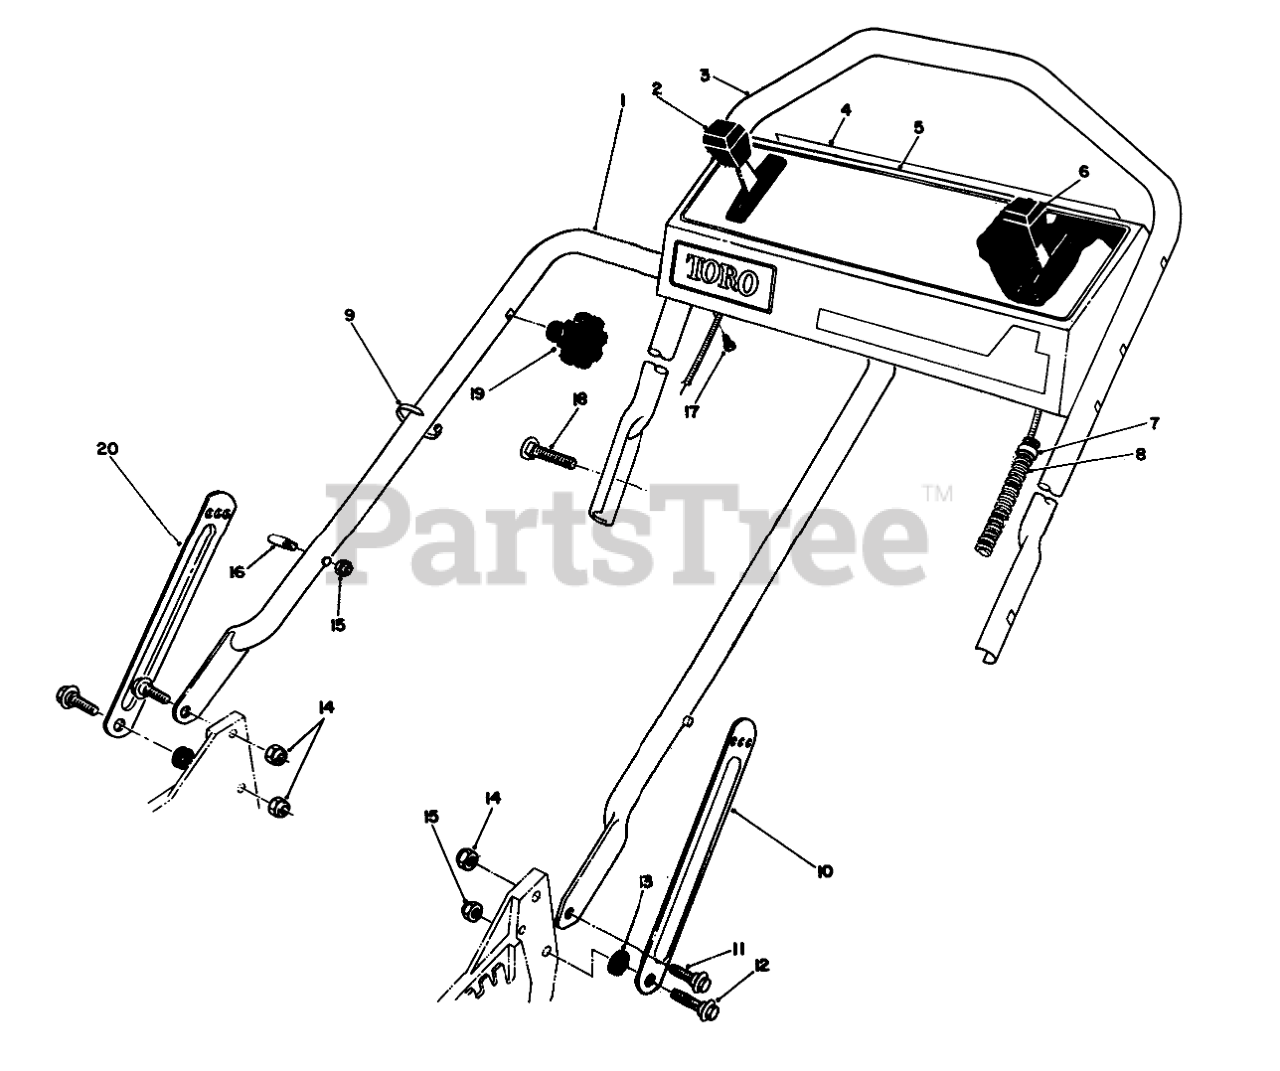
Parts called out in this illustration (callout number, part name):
1	LOWER HANDLE ASM
2	Control-Ground Speed
3	UPPER HANDLE
4	DECAL-PANEL, DANGER
5	Panel-Control (Incl. Ref. #4)
6	THROTTLE CONTROL
7	FITTING-RING
8	CONTROL CABLE COVER
9	TIE-CABLE
10	LH HANDLE LATCH
11	SCREW-SHOULDER
12	SCREW-SHOULDER
13	SPACER
14	NUT-LOCK, NI
15	NUT-LOCK, NI
16	HANDLE PIN
17	SCREW-HWHTF
18	5/16-18 X 2 HNDLE SCREW
20	RH HANDLE LATCH
